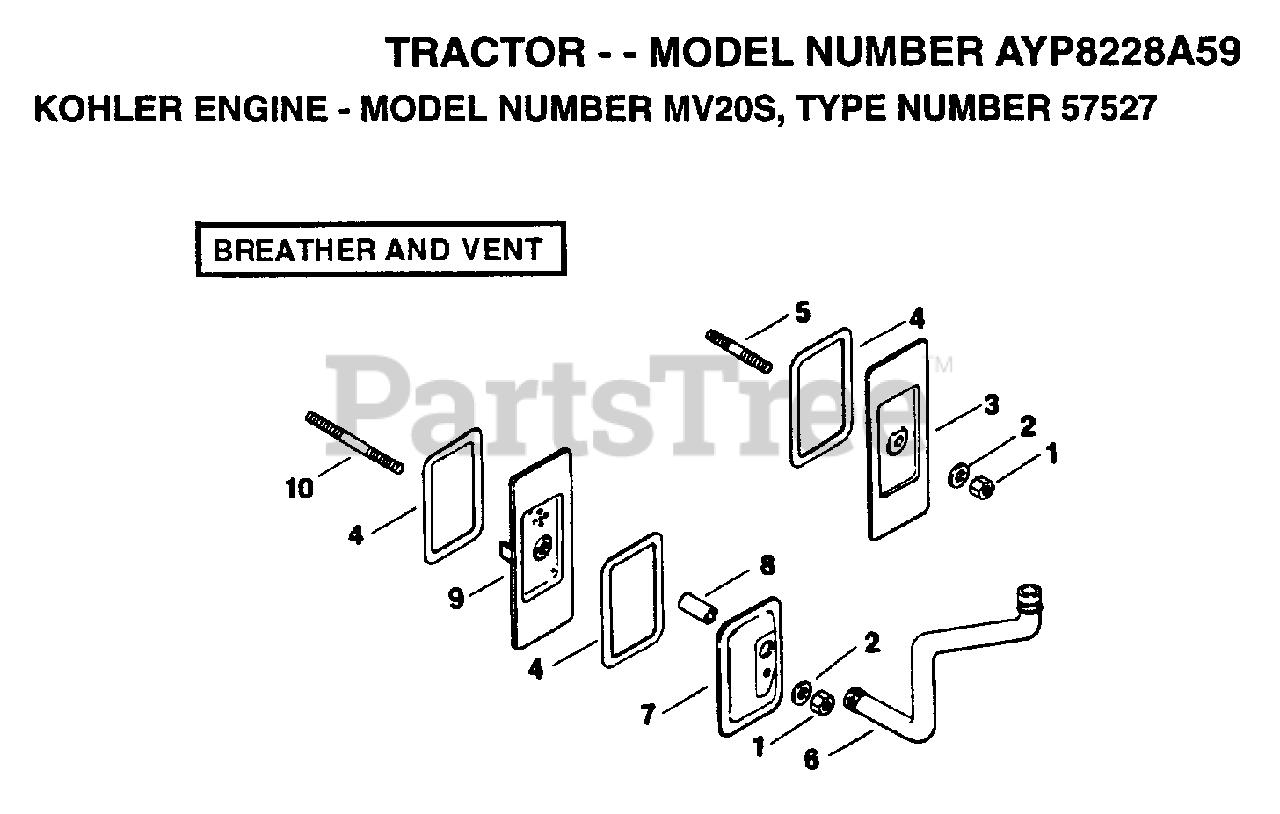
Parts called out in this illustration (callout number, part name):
1	NUT
2	WASHER
3	COVER, #2 CYLINDER VALVE
5	STUD
8	SEAL BREATHER
9	BREATHER ASSY
10	STUD
